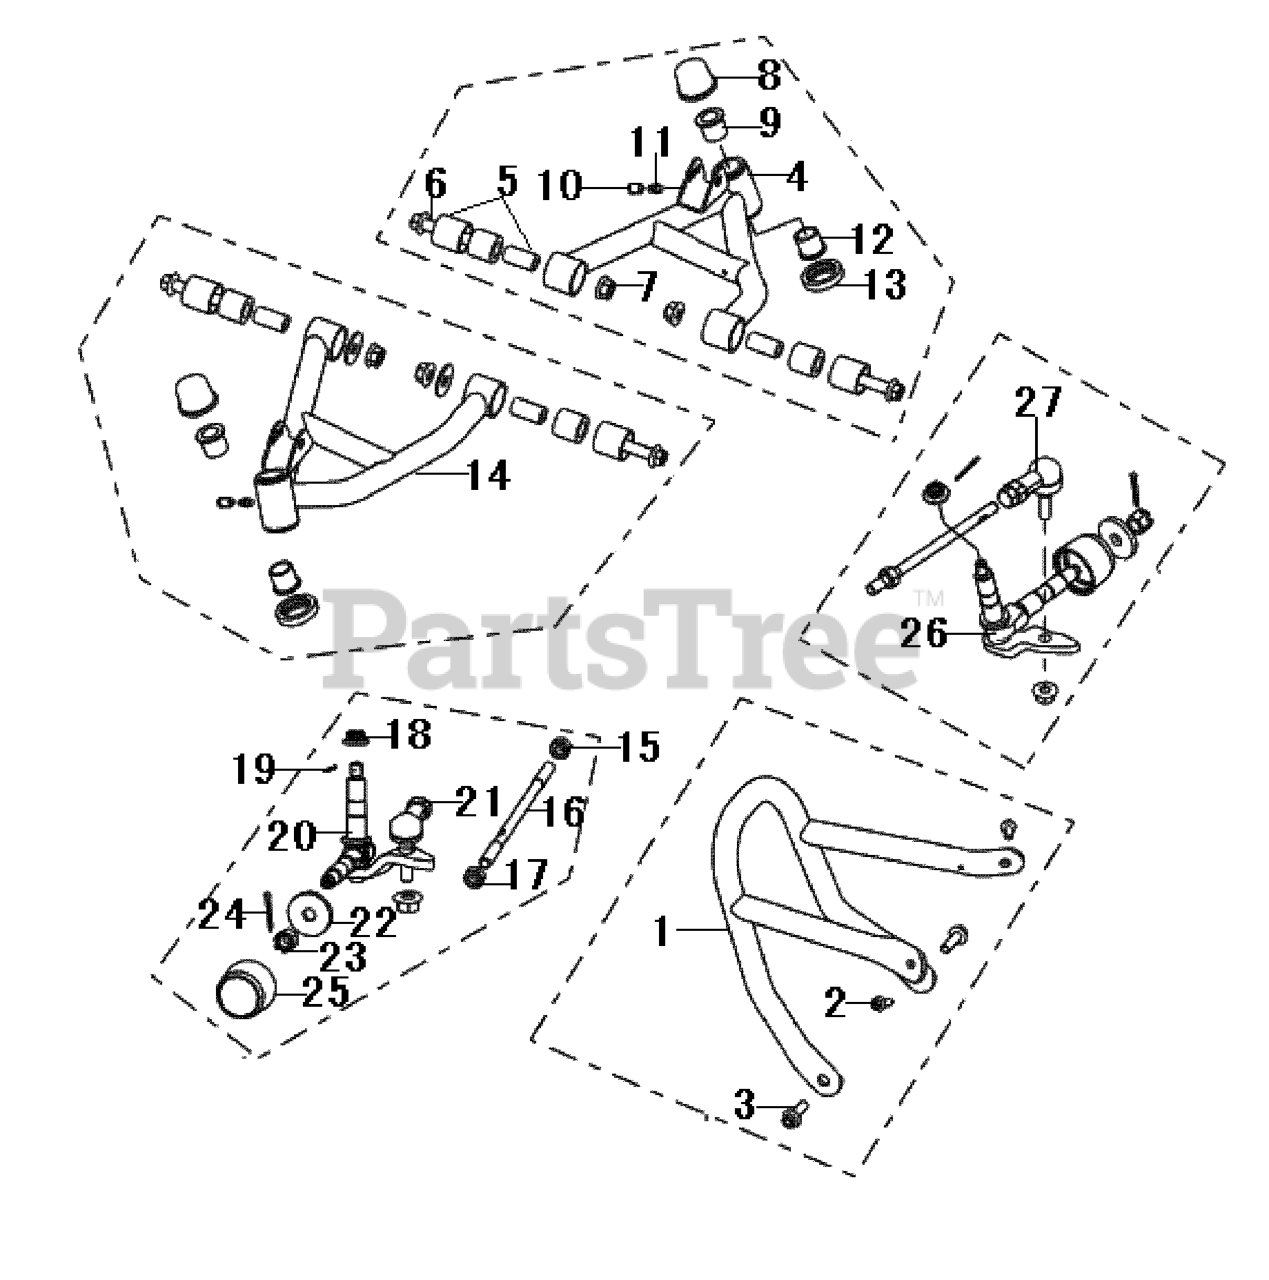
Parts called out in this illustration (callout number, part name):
1	FRONT GUARD
4	A-ARM, RIGHT
5	BUSHING ASSY.
8	DUST CAP
9	BUSHING
10	GREASE FITTING CAP
11	GREASE FITTING
12	BUSHING
14	A-ARM, LEFT
16	TIE ROD
19	SPLIT PIN
20	SPINDLE ASSY, LEFT
21	BALL JOINT
23	NUT, CASTLE
24	PIN, COTTER
25	HUB CAP
26	SPINDLE ASSY., RIGHT
27	BALL JOINT
